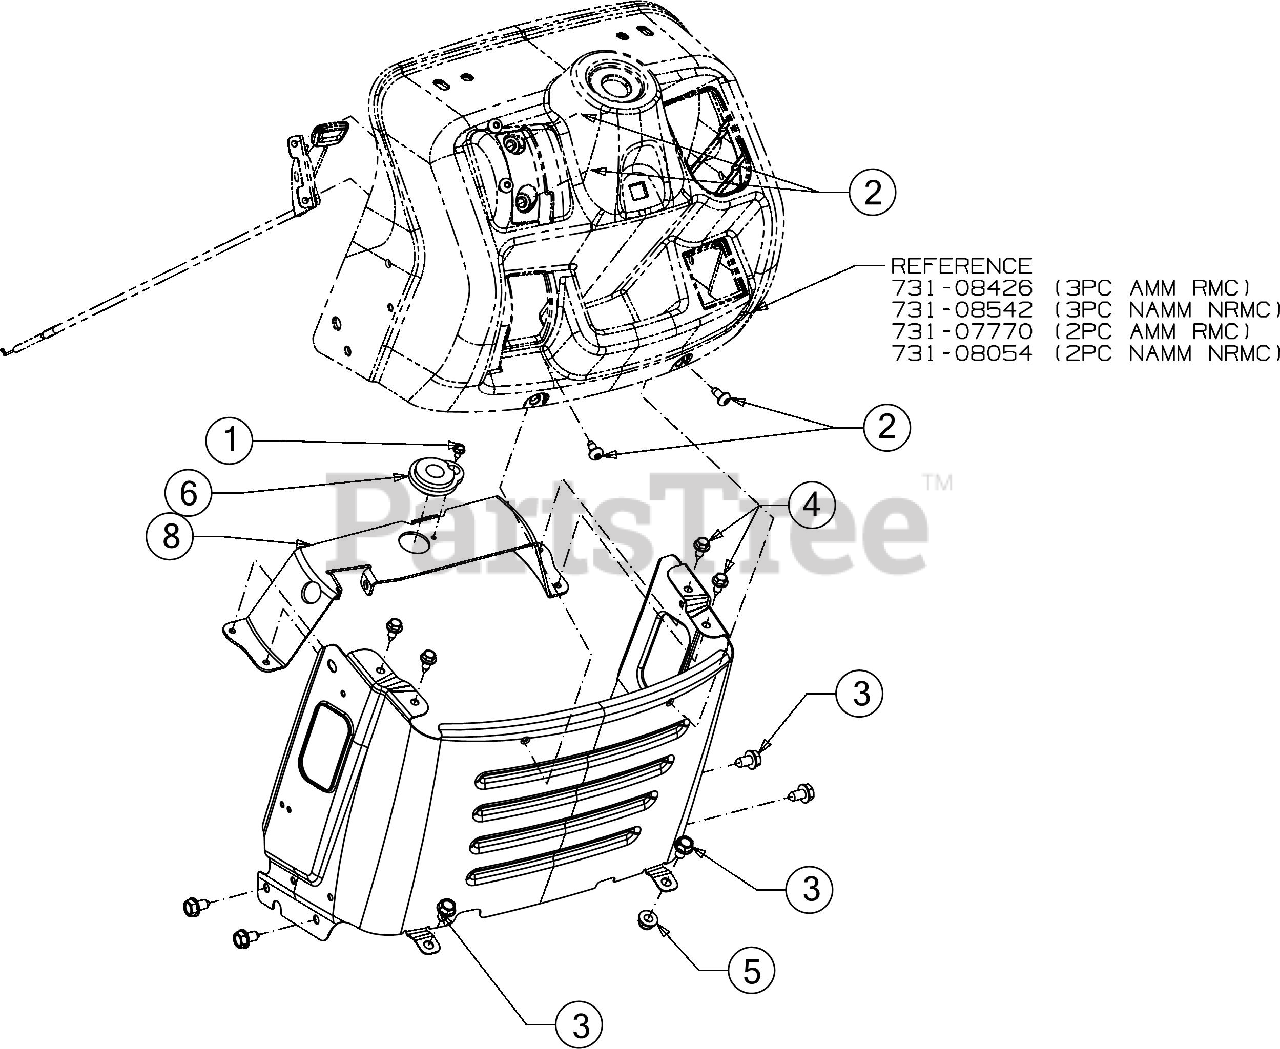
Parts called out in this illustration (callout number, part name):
1	SCREW #10-16 x .625
2	SCREW 1/4-20 x .5
3	SCREW 5/16-18 x .625
4	SCREW 1/4-20X.625
5	FLANGE LOCK NUT 5/16-18
8	STEERING SUPPORT BRACKET
